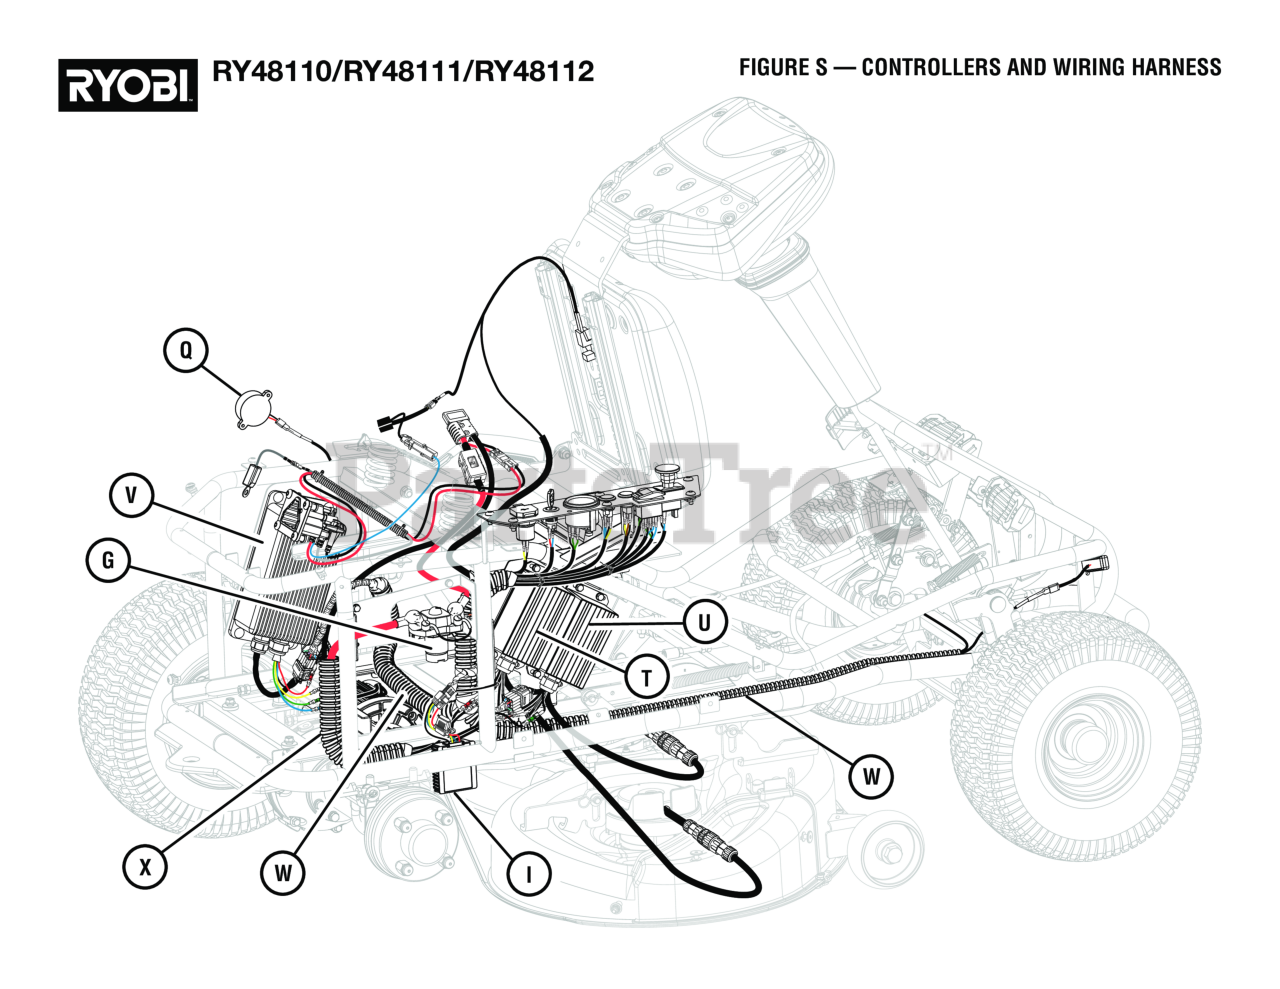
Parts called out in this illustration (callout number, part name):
1	DC to DC Converter, ZTR
2	Master Deck Motor Controller (T)
3	Slave Deck Motor Controller (U)
4	Drive Motor Controller (V)
5	Main Wiring Harness (W)
6	Sub Wiring Harness (X)
7	Main Relay (G)
8	Beeper (Q)
